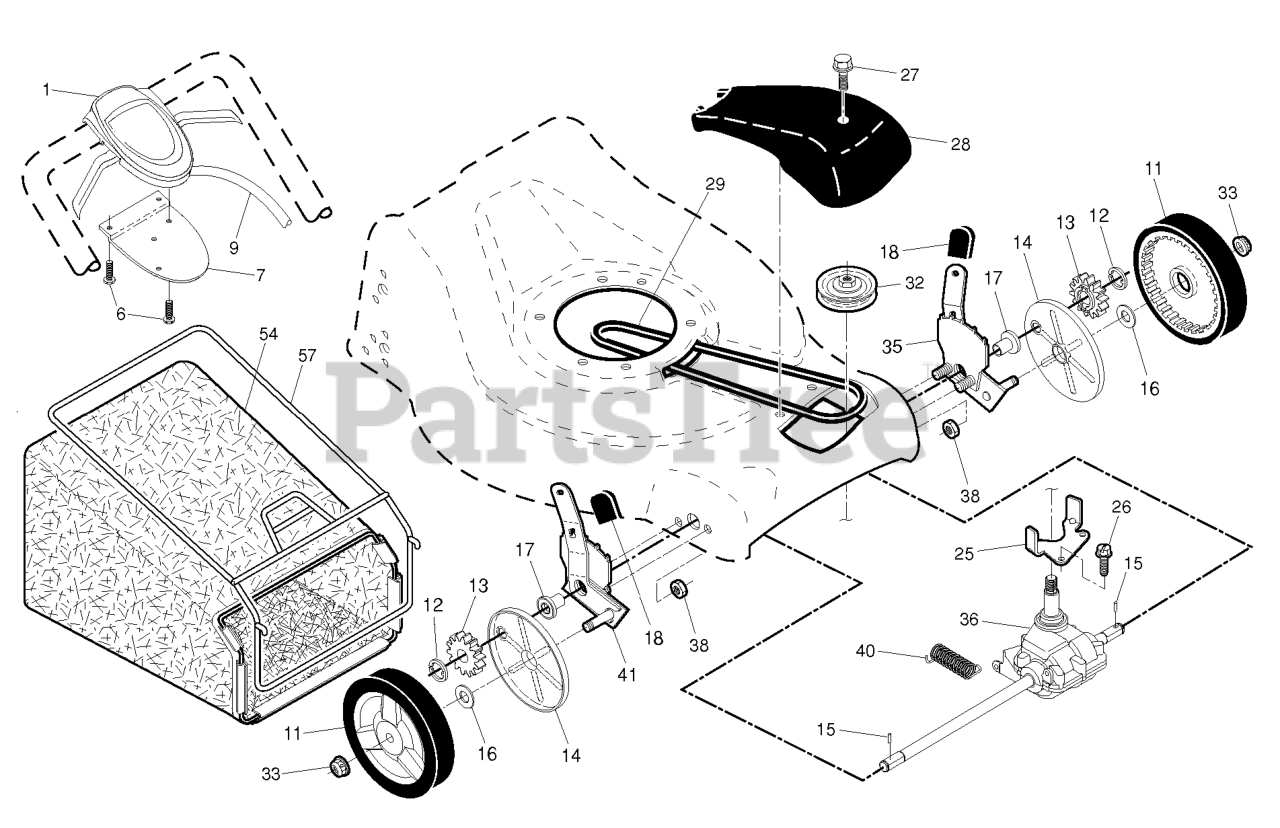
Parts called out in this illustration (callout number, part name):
1	CONTROL.AW2.21FGD.
6	SCREW, PHILLIPS HEAD 10 X 5/8
7	BRACKET.DRIVE.CONTR.GEN2.BLACK
9	RP CABLE.CONTROL.21FGD.GEN2
11	WHEEL.8X1.75.H3SPK.RAD3.GY.BU3
12	E-RING 7/16 RE
13	PINION.14.TEETH.FGD
14	COVER.DUST.WHEEL
15	PAWL, DRIVE
16	WASHER FLUT
17	BEARING.ASM.
18	SELECTOR KNOB
25	BRACKET.BELT.GUIDE.22+FGD.BZP
27	SCREW, HEX HD TAPPING #10-24 1
28	COVER.DRIVE.ASM.185579.CE.WALK
29	BELT.DRIVE.FG
32	RP PULLEY.DRIVE.EZ/VAR.SCREWON
33	NUT.HEX.FLANGE.3/8-16.LO(3 2)
35	KIT ADJUSTER ASM.438151.
36	TRANSMISSION.21.FGD.HT.VST
38	LOCKNUT.NYLOC.1/4-20
41	KIT ADJUSTER ASM.438148
54	RB GBAG.33230247T.SIL.HUSQ.BLU
57	FRAME.GBAG.21.FWGD
